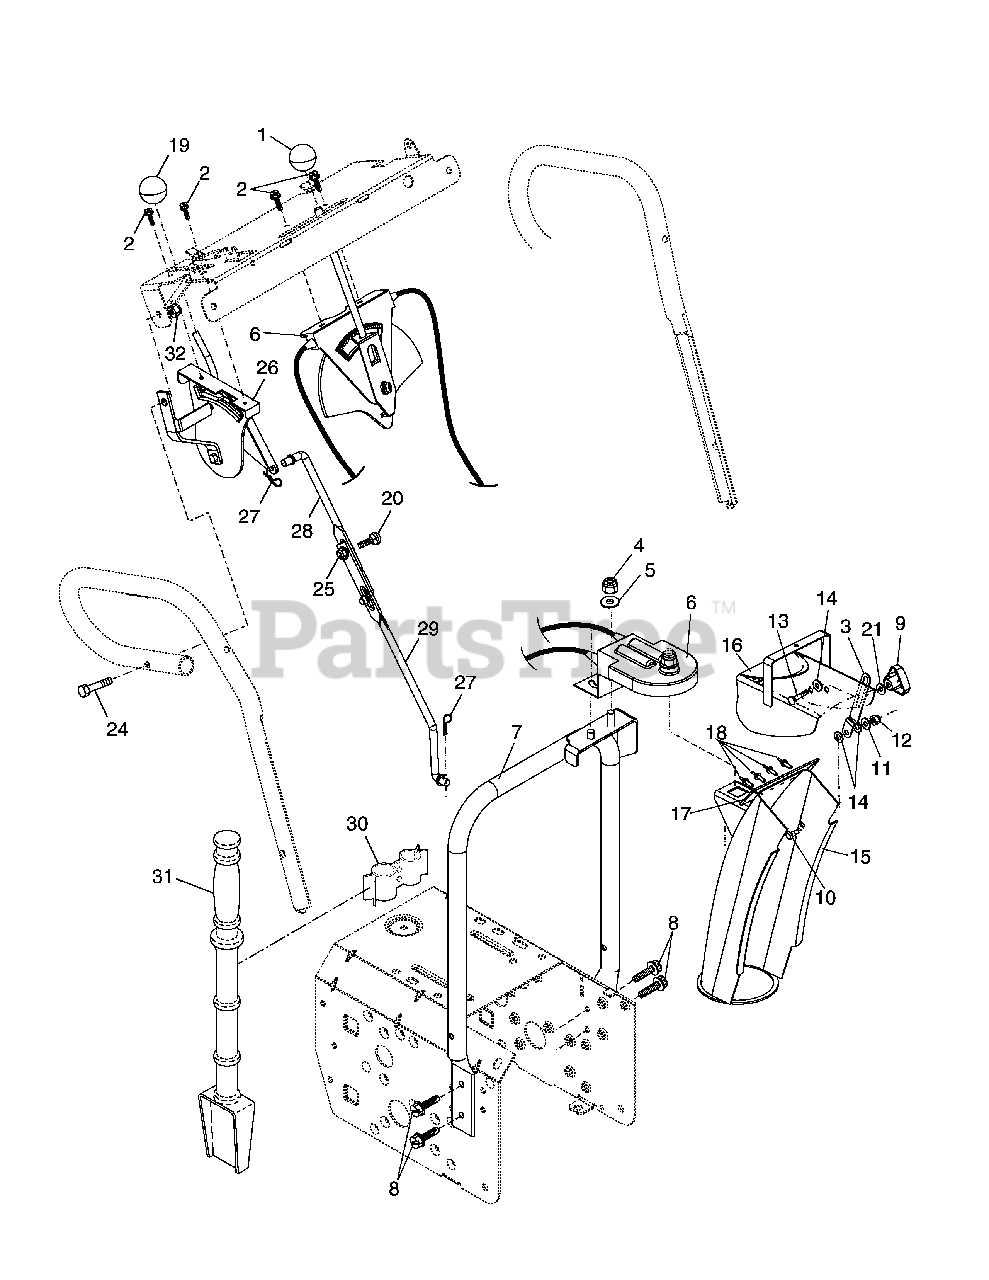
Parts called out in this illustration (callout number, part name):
1	Knob, Lever
2	Screw #10-24 x 5/8
3	Strap, Slotted
4	Nut, Lock 3/8-16
5	Washer, Flat 3/8
6	Control Assembly, Chute Rotater
7	Support, Pivot
8	Screw, Hex Head 5/16-18 x 3/4
9	Knob, Deflector
10	Bolt, Shoulder
11	Washer, Flat 1/4
12	Nut, Lock 1/4-20
13	Bolt, Carriage 5/16-18 x 5/8
14	Washer, Nylon
15	Chute Assembly
16	Deflector Assembly
17	Seal, Deflector
18	Rivet, Blind
19	Knob, Speed Control Lever
20	Bolt, Carriage 5/16-18 x 3/4
21	Washer, Flat
24	Screw, Hex Head 5/16-18 x 1-3/4
25	Nut, Lock 5/16-18
26	Lever Assembly, Speed Control
27	Retainer, Hairpin
28	Rod, Upper, Speed Control
29	Rod, Lower, Speed Control
30	Clamp, Clean-Out Tool
31	Tool, Clean-Out
32	Nut, Lock 5/16-18
